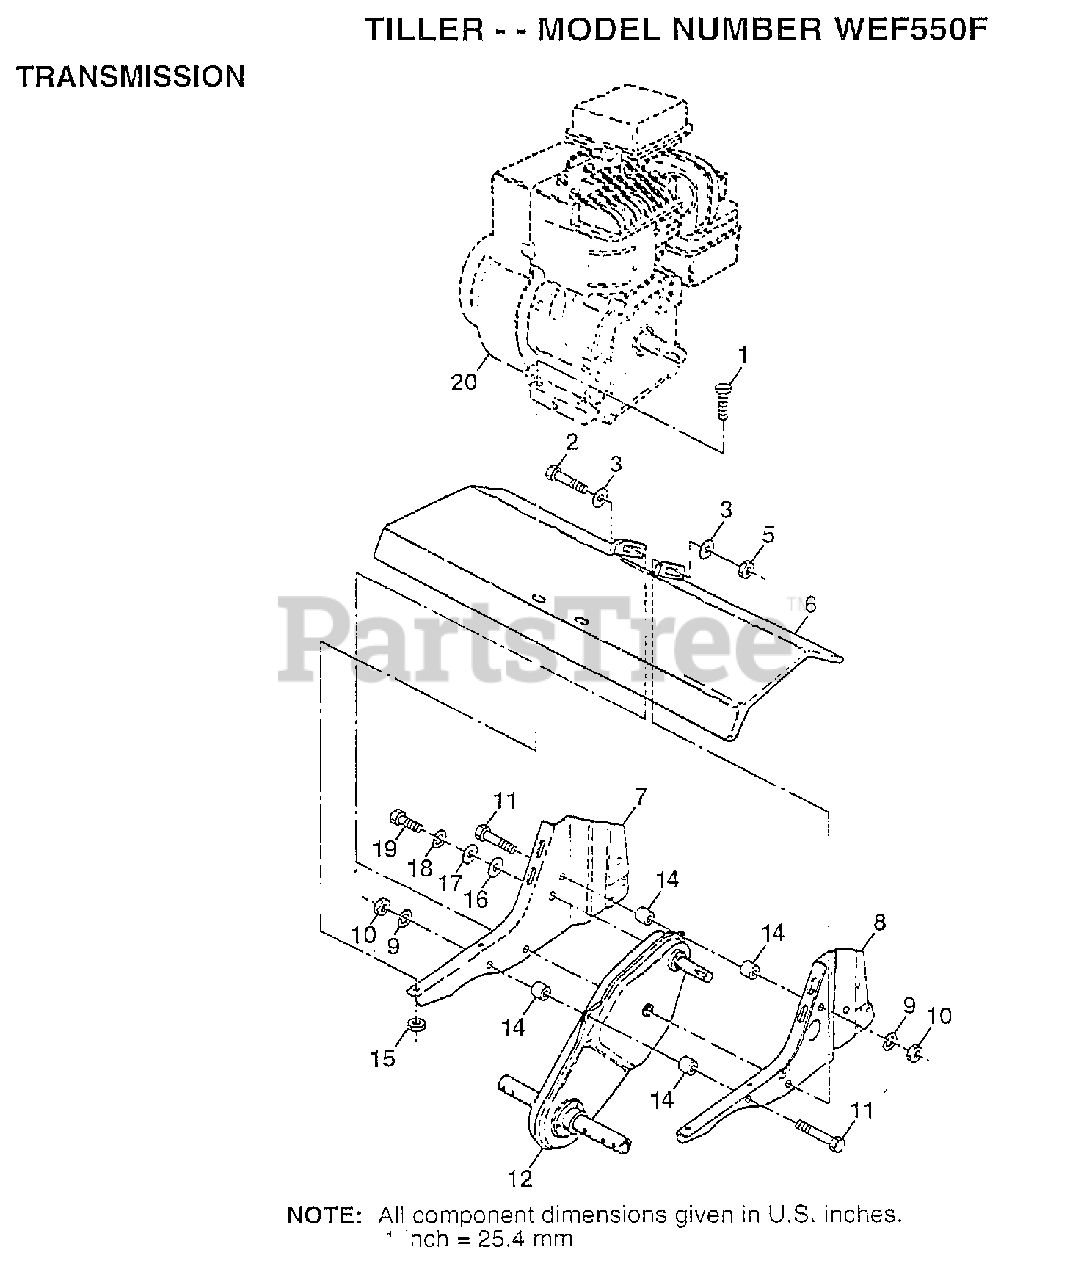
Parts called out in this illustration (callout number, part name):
1	BOLT.HEX.5/16-1.5
2	BOLT HEX 3/8-16
3	WASHER
5	NUT
6	SHIELD.PNT.TINE
8	BRACKET.ENG.LH.
9	LOCKWASHER
10	NUT.HEX.5/16-18
14	SPLIT SPACER RT
16	WASHER
17	WASHER
18	LOCKWASHER
19	BOLT
